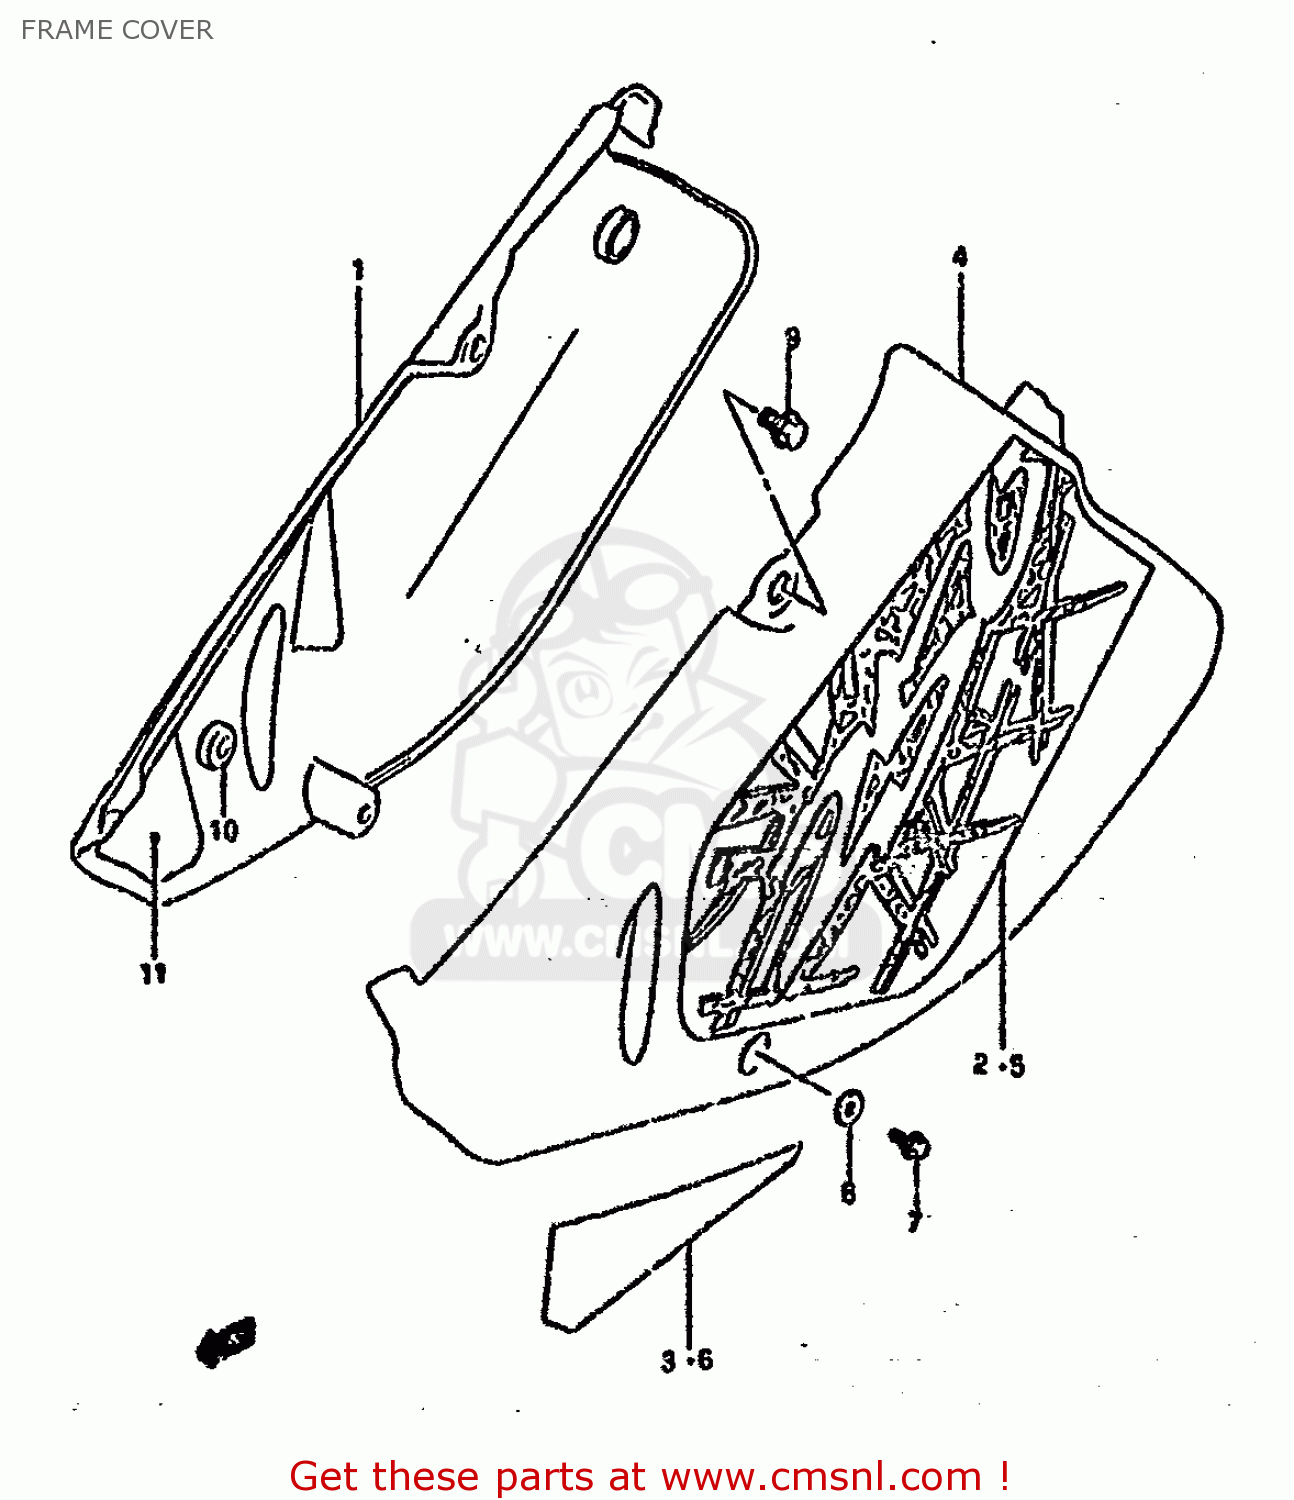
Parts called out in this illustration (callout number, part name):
1	COVER,FRAME,RIGHT
2	EMBLEM,FRAME COVER,RIGHT
3	EMBLEM,FRAME COVER,RIGHT
4	COVER,FRAME,LEFT
5	EMBLEM,FRAME COVER,LEFT
6	EMBLEM,FRAME COVER,LEFT
7	BOLT
8	WASHER
9	BOLT
10	CUSHION
11	SHIELD,FRAME COVER,RIGHT H
